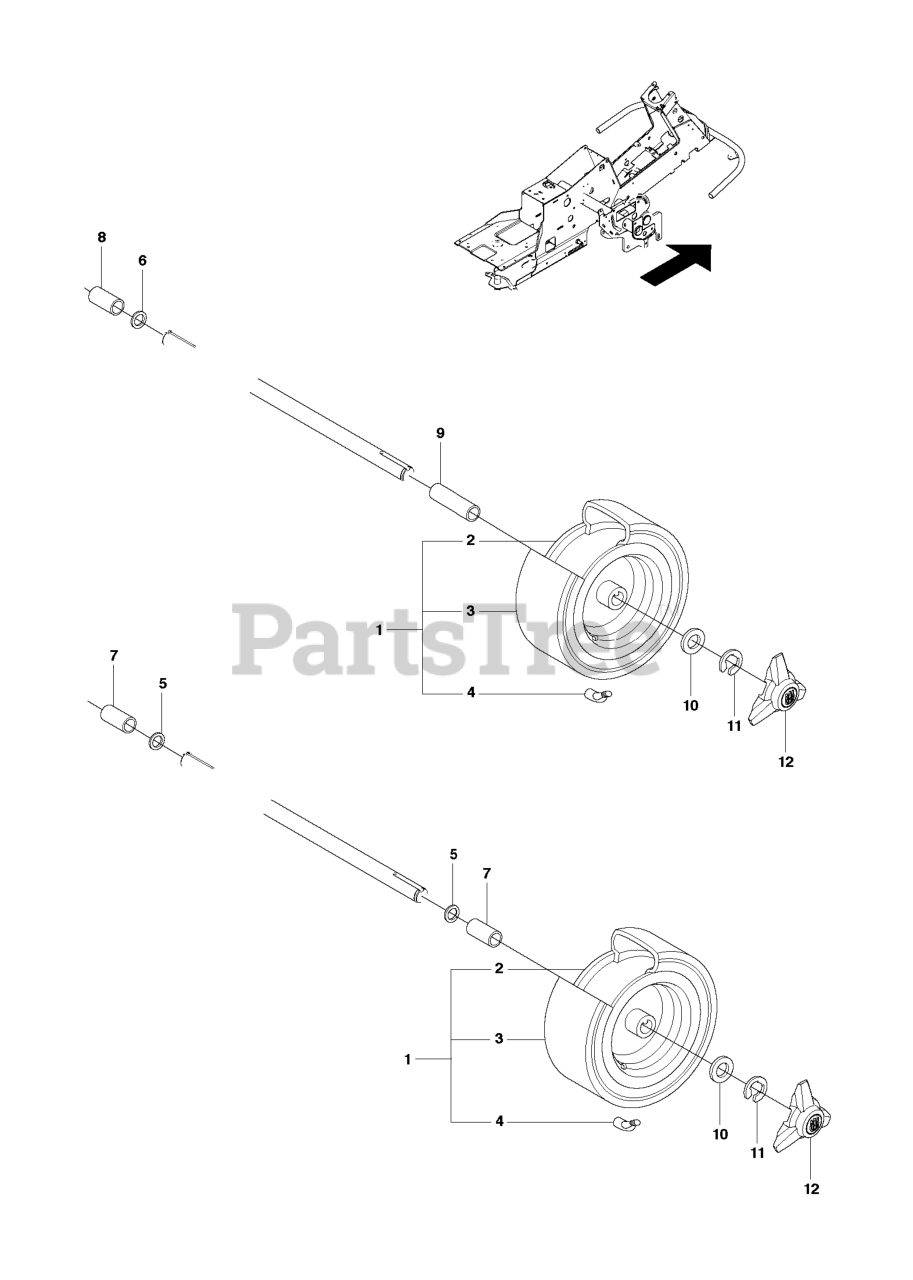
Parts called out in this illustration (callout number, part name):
2	RP RIM
7	SPACE SLEEVE
11	RETAINING RING
